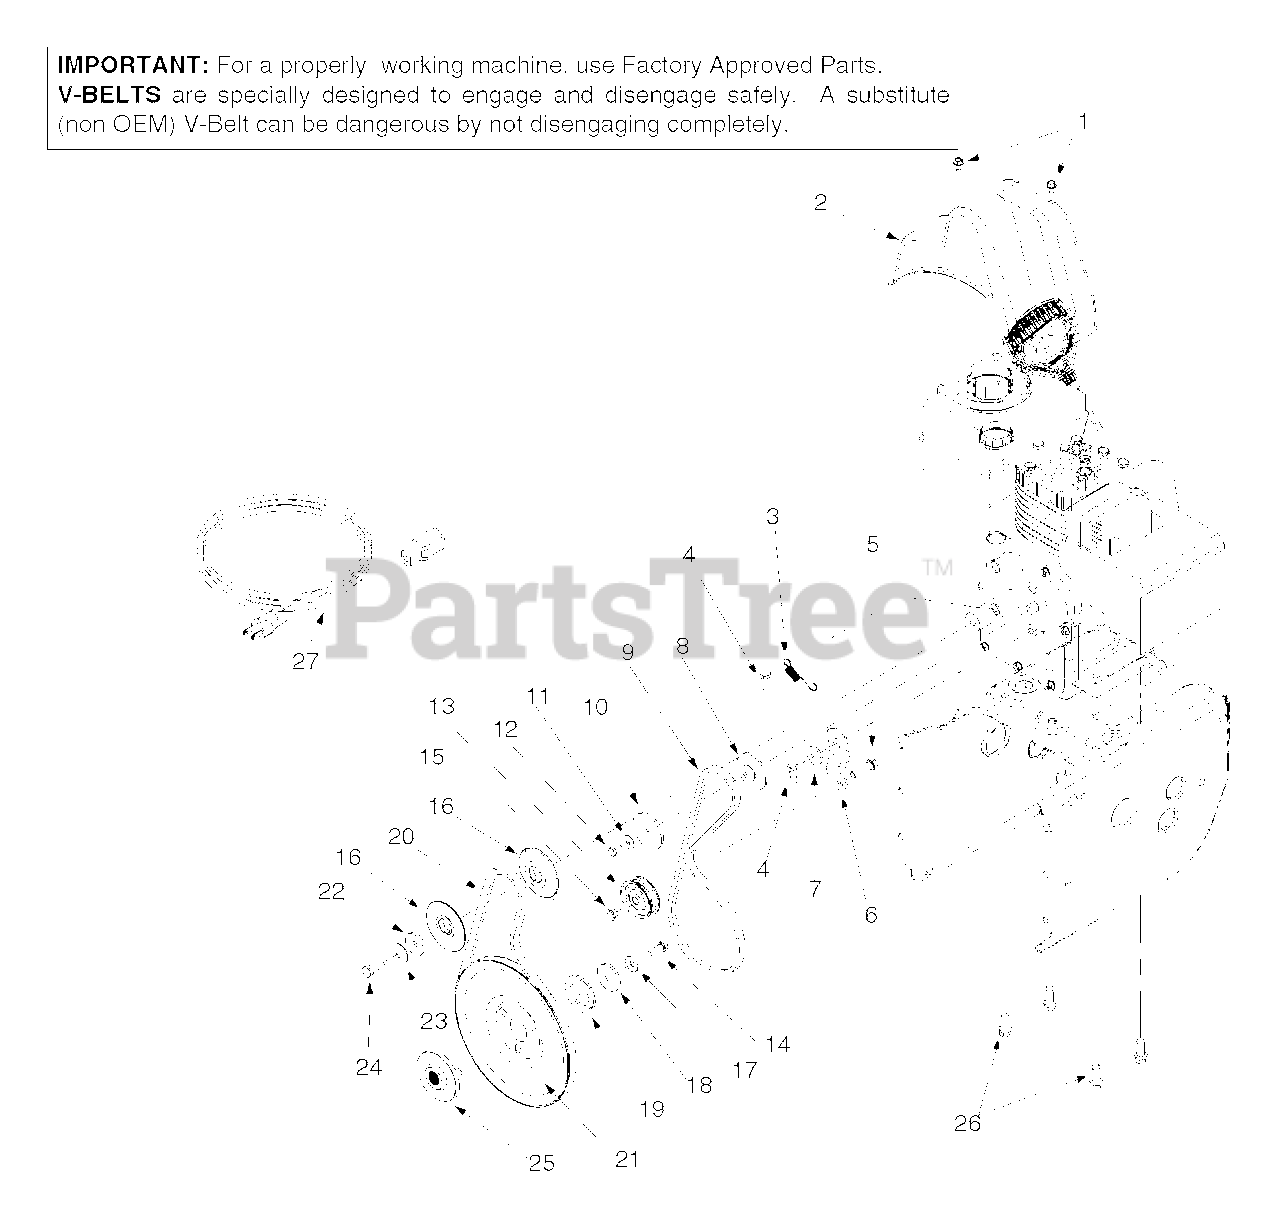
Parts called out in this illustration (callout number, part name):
1	Hex Washer Screw 1/4-20 x.5
2	Belt Cover
3	Extension Spring
4	Hex Screw 5/16-24 x .75
5	Hex Cap Screw 3/8-16 x 1.25
8	Pulley Half
9	V-Belt
10	Pulley Half
11	Bell Washer
12	Hex Cap Screw 1/4-28 x .50
13	Flat Idler
14	Lock Cap Screw 5/16-24
15	Lock Jam Nut 3/8-16
16	Pulley Half
17	Bell Washer
18	Flat Washer
19	Washer
20	Belt
21	Auger Pulley
22	Flat Washer
23	Bell Washer
24	Hex Cap Screw 3/8-24
25	Pulley
26	Hex Washer Screw 3/8-16 x 1.0
27	Extension Cord
